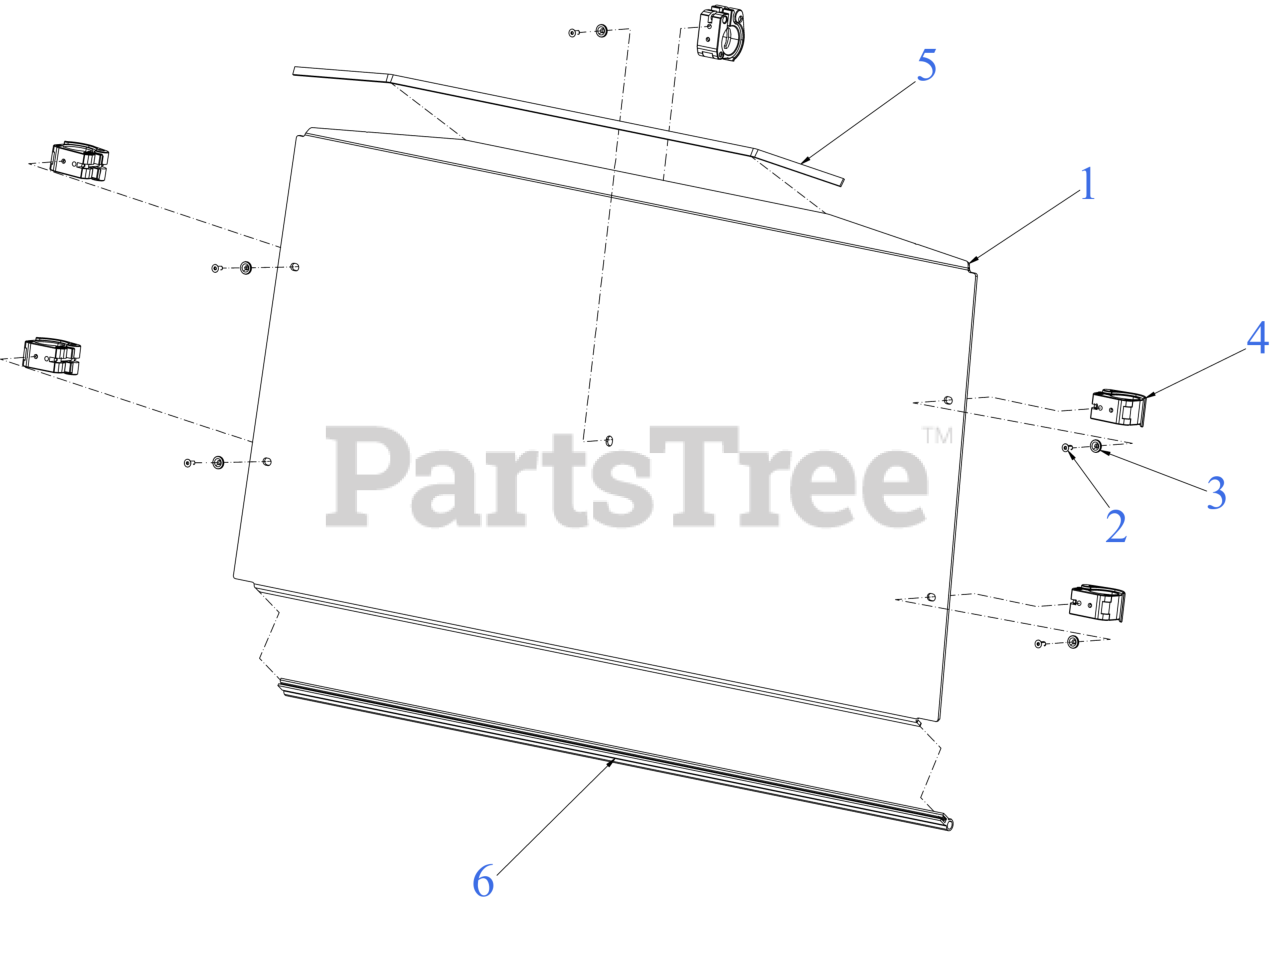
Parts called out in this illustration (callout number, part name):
1	DUST SHIELD
2	BUTTON HEAD SCREW M6x12
6	BULB CHANNEL SEAL
